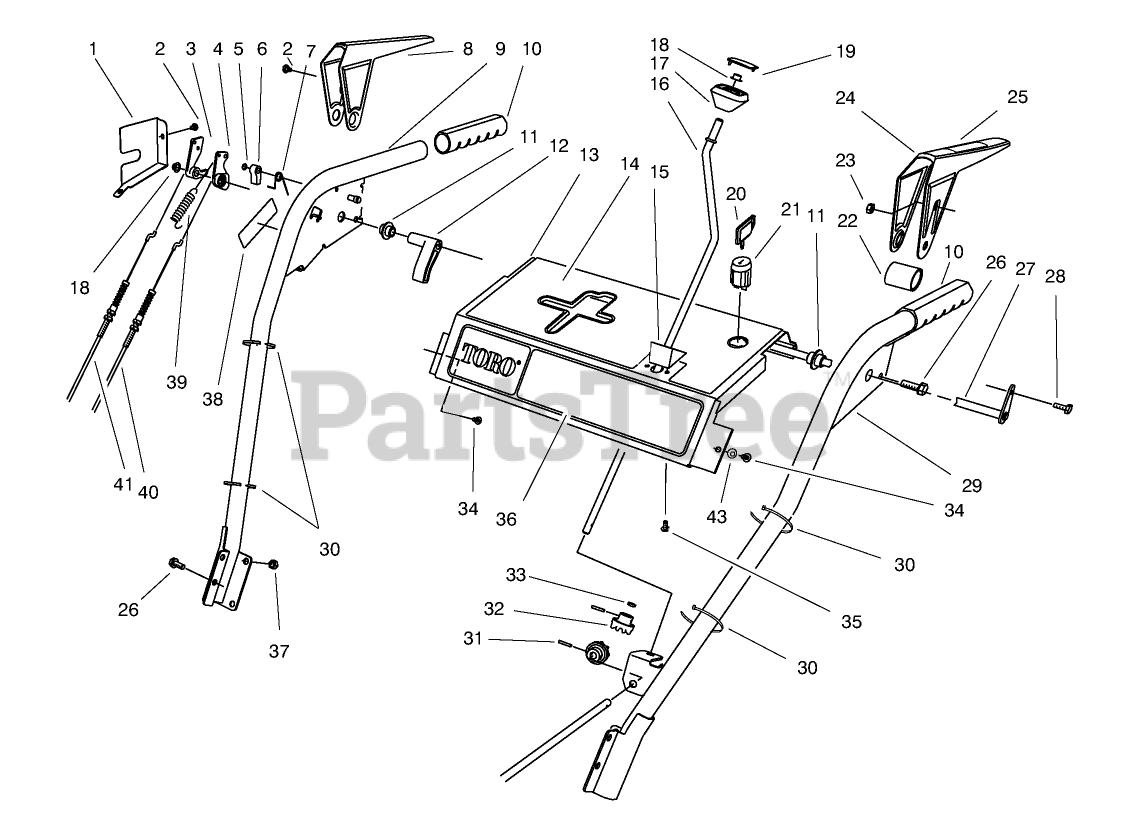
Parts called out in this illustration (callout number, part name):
1	Pin, Spring (Incl. Ref. #7)
2	Washer
3	Retainer
4	Washer
5	Spring-Brake
6	Dog-Starter
7	Spring-Dog
8	Pulley and Rewind Spring ASM
11	Starter Housing ASM
12	Rope-Starter (98 cut to length)
13	Handle-Starter, Mitten Grip
